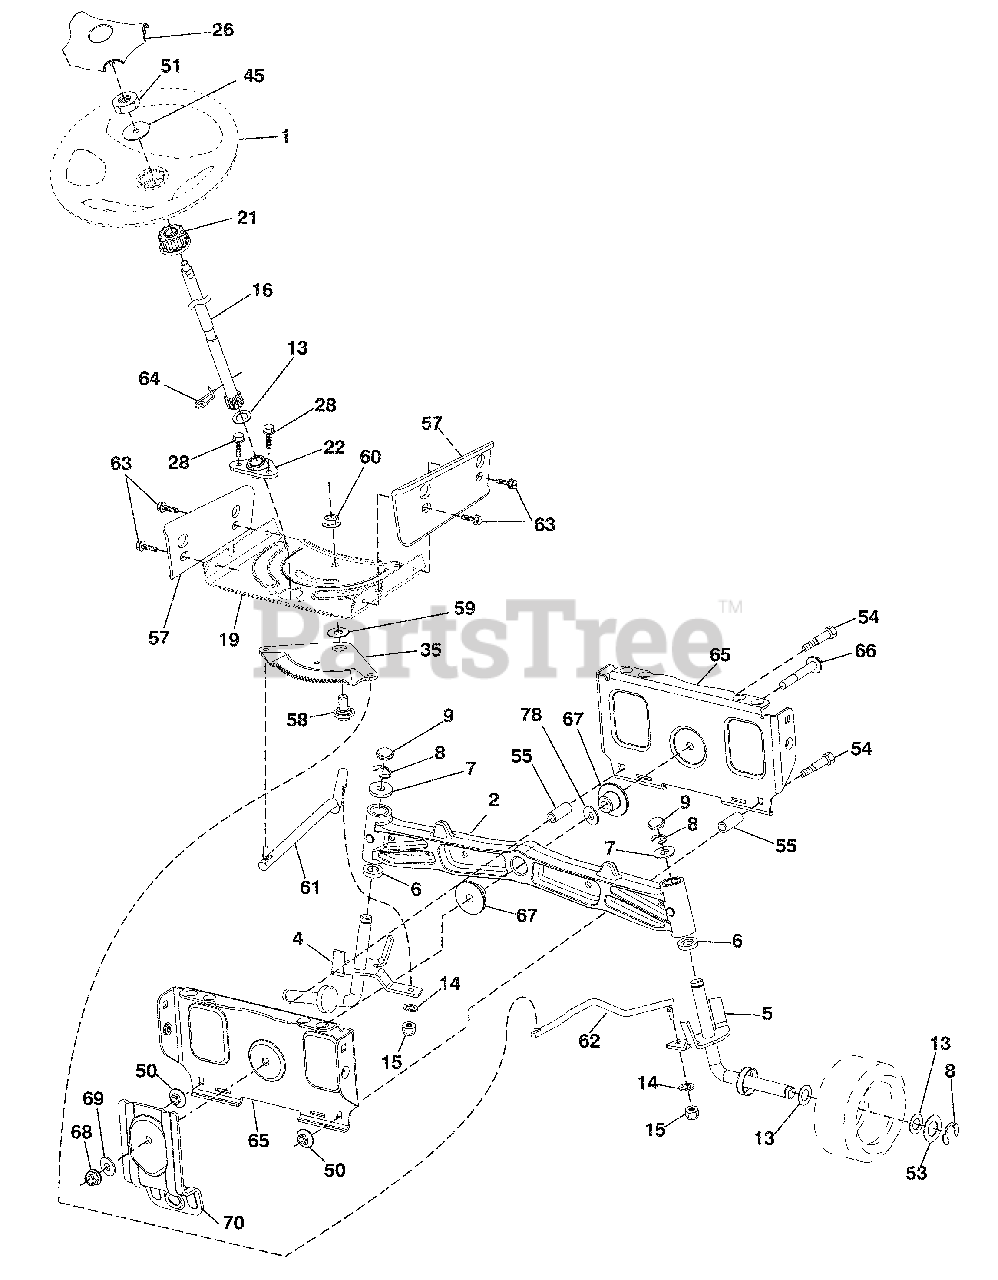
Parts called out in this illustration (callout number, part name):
1	Wheel, Steering
2	Axle Asm., Front
4	Spindle Asm., LH
5	Spindle Asm., RH
6	Bearing, Race Thrust Harden
7	Washer 25/32 x 1-5/8 x 16 Ga.
8	Ring, Klip #T5304-75
9	Cap, Spindle
13	Washer 25/32 x 1-1/4 x 16 Ga.
14	Washer, Lock Hvy Hlcl Spr 3/8
15	Nut, Crown Lock 3/8-24 unf
16	Shaft Steering
19	Plate Steering
21	Adapter, Wheel Steering
22	Bushing, Strg. Blk
26	Insert, Wheel Steering
28	Screw 3/8-16 x 3/4
35	Gear, Sector Plate
45	Washer 9/16 ID x 2-3/8 OD 12 Ga.
50	Nut Lock 3/8-16 UNC
51	Nut Hex Jam Toplock 1/2-20 unf
53	Washer Hardened .793 x 1.637 x .060
54	Bolt Hex 3/8-16 UNc x 2-1/4
55	Spacer Brace Axle
57	Bracket Upstop
58	Bolt Shoulder Sector Pivot CFM
59	Washer Thrust Sector Steering
60	Nut Flange Lock 5/8-11
61	Draglink LH
62	Draglink, RH
63	Screw 5/16-18 x 3/4
64	Retainer Clip Spring Steering
65	Brace Axle Front
66	Bolt Hex Fghd 7/16-14 x 3 Serr
67	Bushing PM Front Axle
68	Nut Lock Flange 7/16-14 Gr. 5
69	Washer 1.5 x .505 x .118
70	Bracket Deck Susp. Front
78	Washer Thrust
